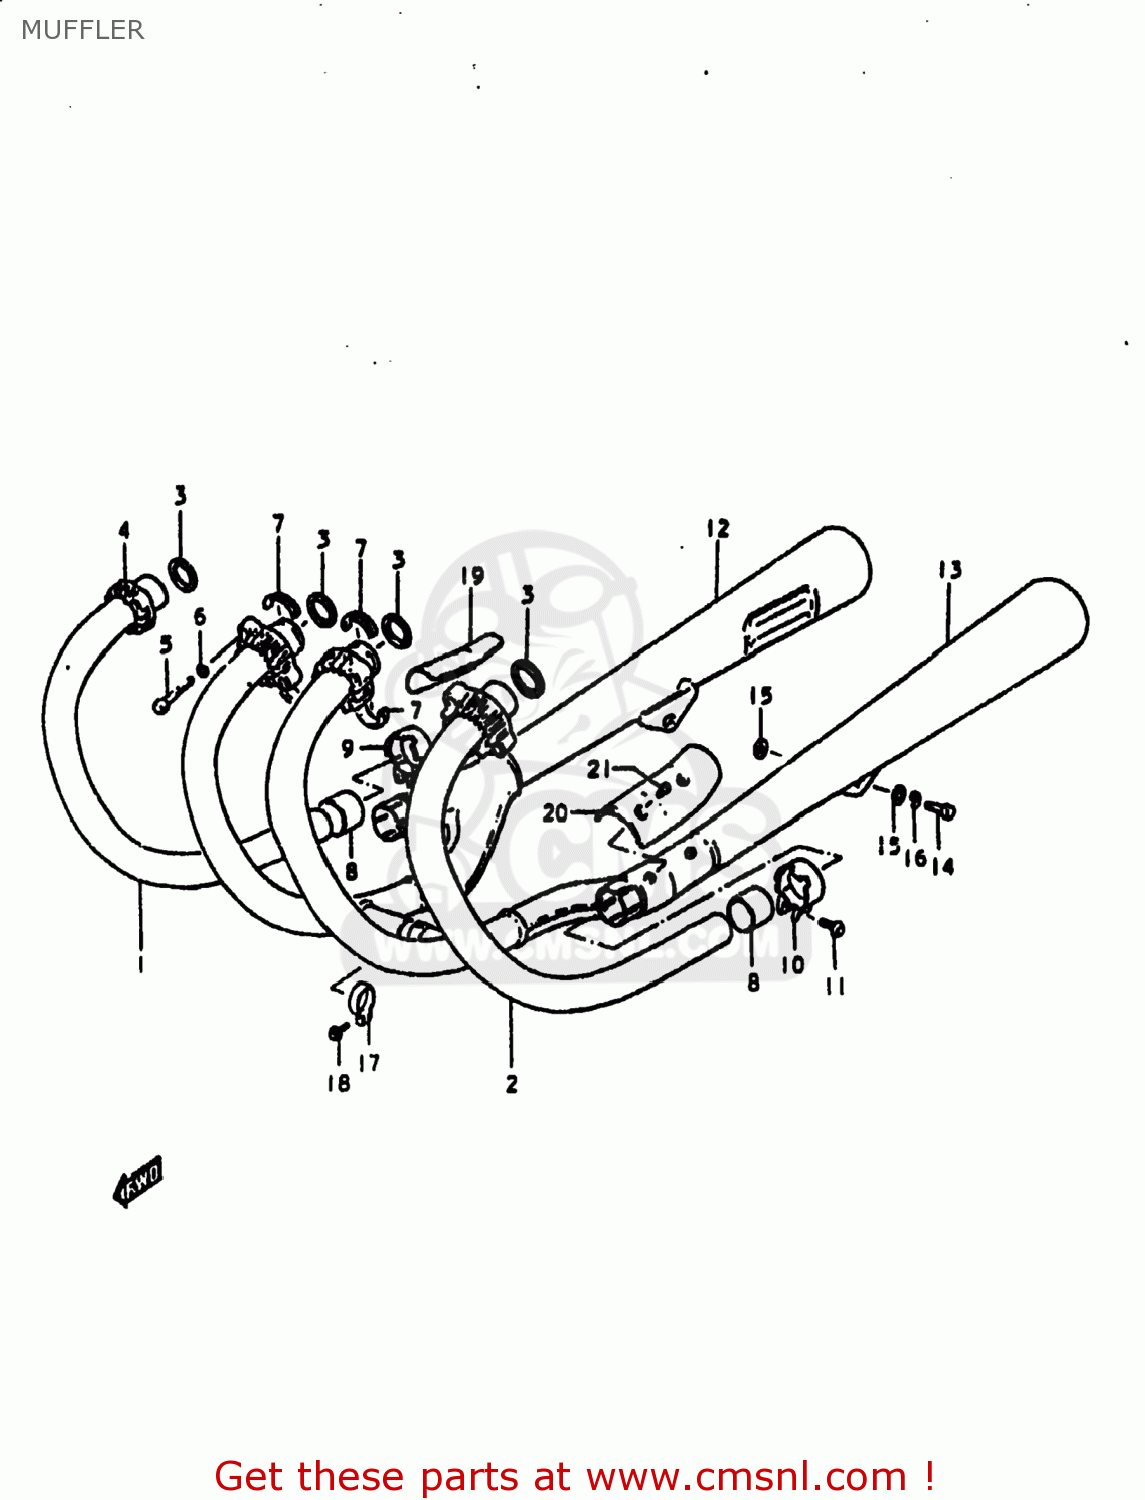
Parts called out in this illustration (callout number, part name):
1	PIPE,EXHAUST,R
2	PIPE,EXHAUST,L
3	GASKET,EXHAUST PIPE (NAS)
4	CLAMP,EXHAUST PIPE
5	BOLT
6	LOCK WASHER
7	PLATE,EXHAUST
8	CONNECTOR,MUFFLER
9	CLAMP,MUFFLER CONNECTOR,R
10	CLAMP,MUFFLER CONNECTOR,L
11	BOLT
12	BODY,MUFFLER
13	BODY,MUFFLER
14	BOLT 10X30
15	WASHER
16	LOCK WASHER
17	CLAMP
18	BOLT
19	COVER,MUFFLER
20	COVER,MUFFLER,LEFT
21	SCREW
